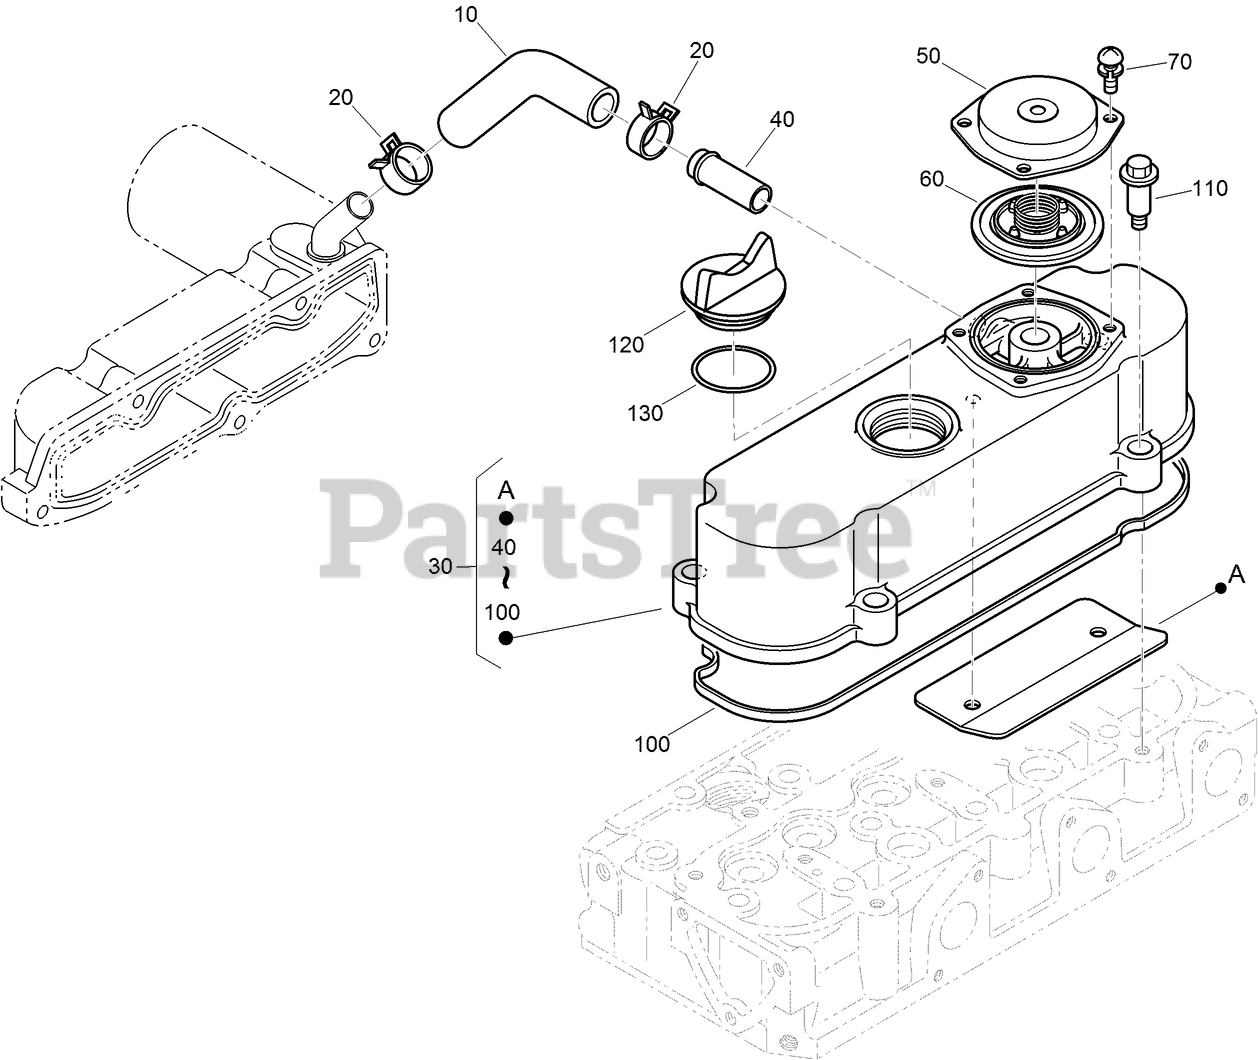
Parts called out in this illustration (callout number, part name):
10	TUBE-BREATHER
20	CLAMP-HOSE
30	CYLINDER HEAD COVER ASM
40	PIPE-RETURN, WATER
50	COVER-BREATHER
60	VALVE-BREATHER
70	SCREW (WITH WASHER)
100	GASKET-COVER, HEAD
120	PLUG-FILLER, OIL
130	O-RING
